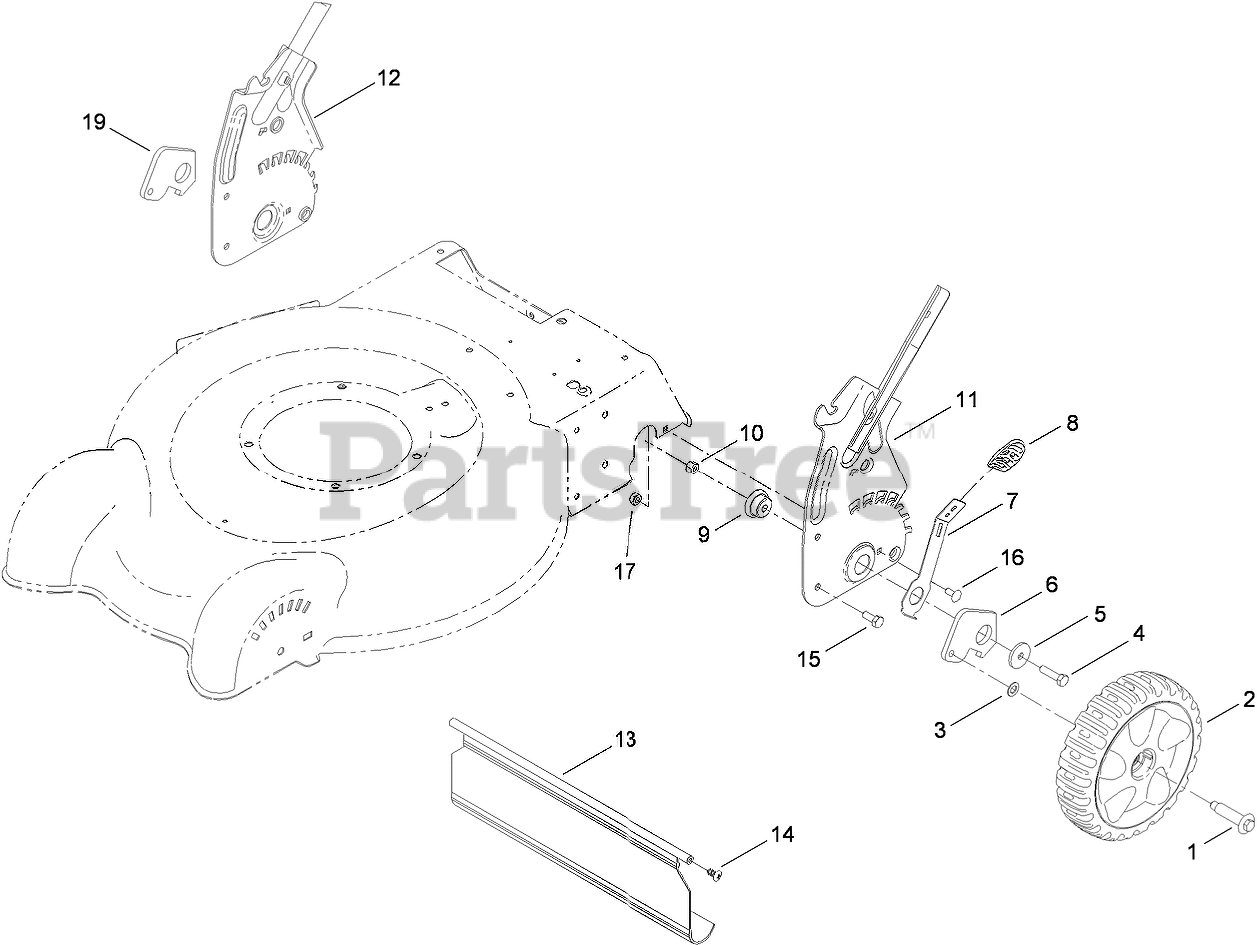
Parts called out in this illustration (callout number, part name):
1	BOLT-SHOULDER
2	8 INCH WHEEL AND TIRE ASM
3	WASHER
4	SCREW-HH
5	Washer-Flat
6	Arm-Pivot, Rear (LH)
7	Arm-Spring
8	Knob-Lever, HOC
9	Bushing-Mount, HOC
10	NUT-LOCK, NI
13	SHIELD-TRAILING
14	SCREW-PTH
15	SCREW-HH
16	SCREW-CARR
17	NUT-LOCK, NI
19	ARM-PIVOT, REAR (RH)
